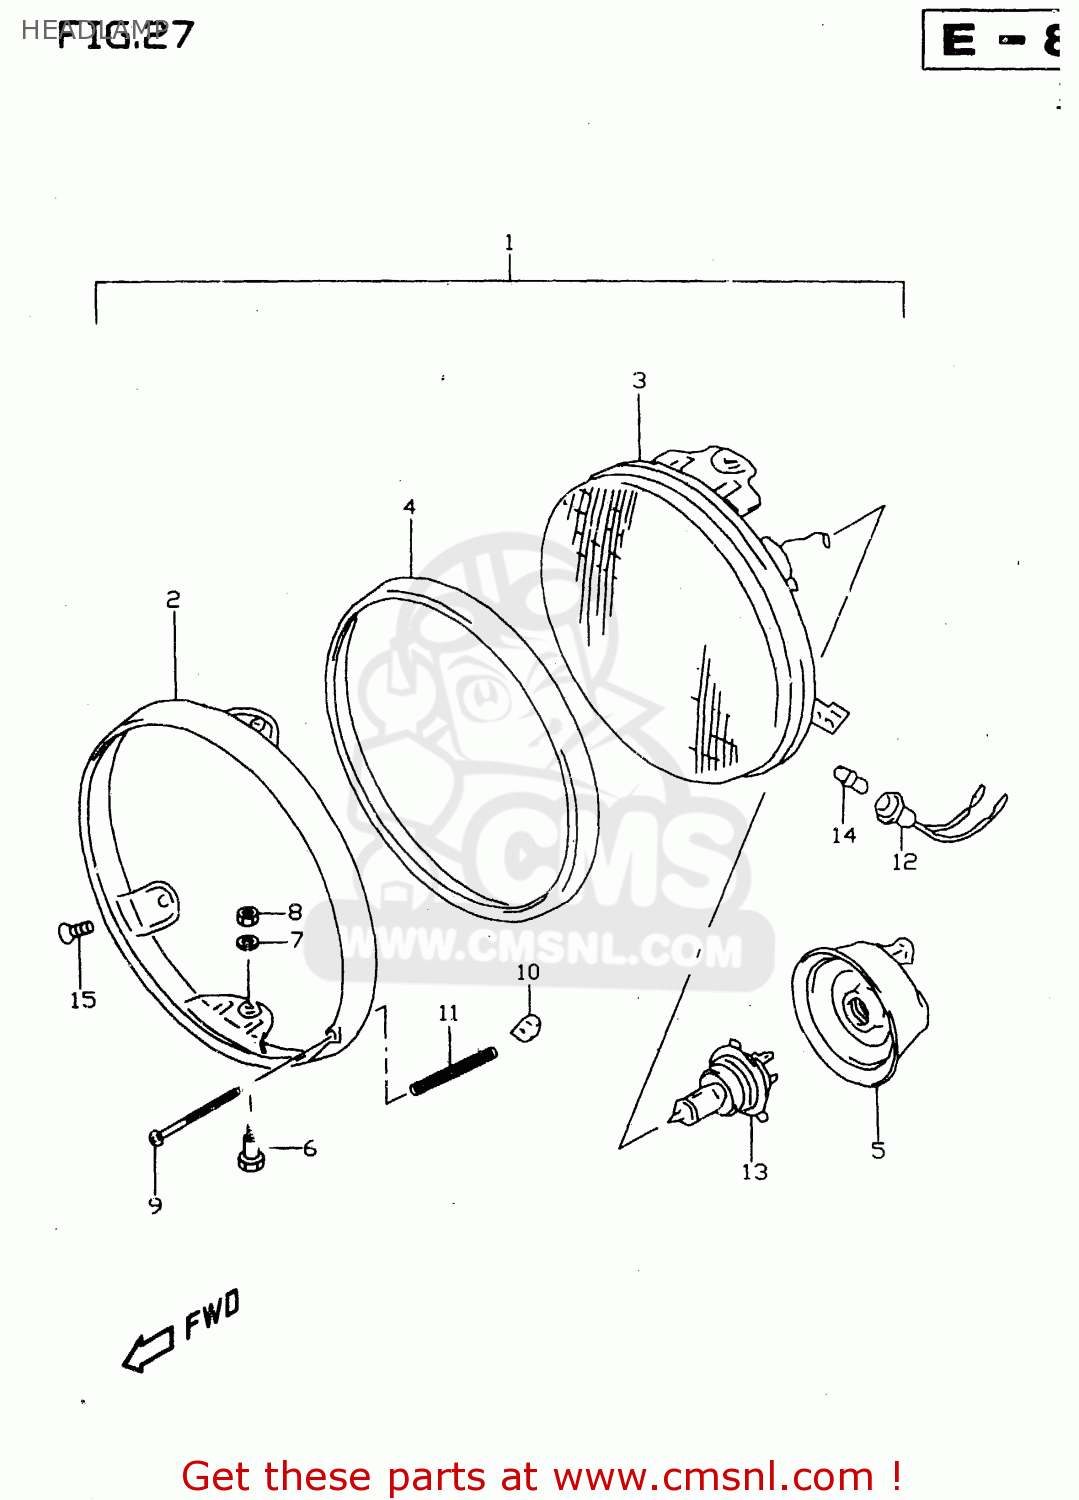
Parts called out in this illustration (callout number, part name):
1	HEADLAMP ASSY
2	RIM,HEADLAMP
3	LAMP UNIT
4	RING
5	COVER,SOCKET
6	H/LAMP LENS UNIT FITING SCRE
7	WASHER,LOCK
8	NUT
9	SCREW
10	NUT
11	SPRING,ADJUSTING
12	SOCKET,PARKING LAMP
13	BULB(12V60/55W,H4)
14	BULB(12V4W)
15	SCREW(5X12)
